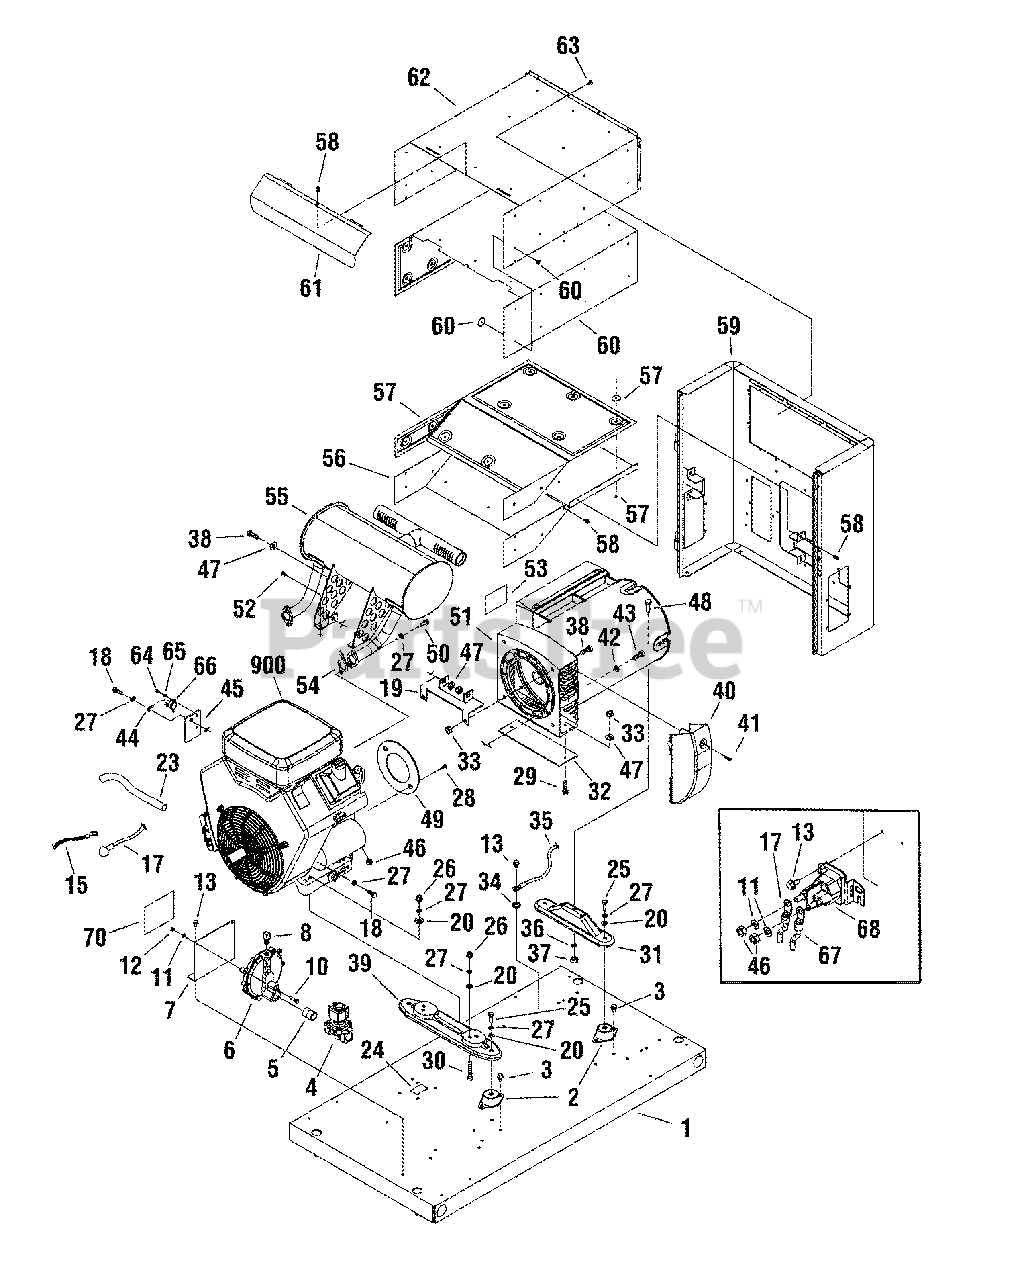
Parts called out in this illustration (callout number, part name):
2	MOUNT, Vibration
4	SOLENOID, Gas Fuel
6	REGULATOR, NG/LPG
10	* CAPSCREW, Hex Head
11	WASHER, Lock, 1/4
12	* NUT, M6-1
13	BOLT
15	CABLE, Battery, Black
17	CABLE, Battery, Red
18	* CAPSCREW, Hex Head, M8 - 1-1/4 x 16
20	* WASHER, Flat, 5/16-M8
23	HOSE, Oil Drain
24	DECAL, Oil Drain
25	* CAPSCREW, Hex Head, 5/16-18 x 1
26	* NUT, 5/16-18
27	* WASHER, Lock, 5/16-M8
28	* CAPSCREW, Hex Head, SEMS, 5/16-24 x 3/4
29	* CAPSCREW, Hex Head, 1/4-20 x 1
30	* CAPSCREW, Hex Head, 5/16-18 x 1-3/4
31	SUPPORT, Alternator
34	* WASHER, Shakeproof, EXT, M6-1/4
36	* WASHER, Lock, M10
37	* NUT, Hex, M10 - 1-1/2
38	* CAPSCREW, Hex Head, 1/4-20 x 3/4
39	SUPPORT, Engine
42	* WASHER, Lock, 3/8
43	* CAPSCREW, Hex Head, 3/8-16 x 1-1/4
45	PLATE, Temp Switch
46	* NUT, Hex, 1/4-20
47	* WASHER, Flat, M6-1/4
48	* CAPSCREW, Hex Head, M10 - 1-1/2
51	ALTERNATOR, Complete
53	DECAL
59	BULKHEAD, Alternator
62	BOX, Muffler Top
64	* SCREW, Phillips Head, 4-40 x 3/16
65	* WASHER, Lock, #4
66	SWITCH, Temp
68	SOLENOID / BRACKET
900	** ENGINE
